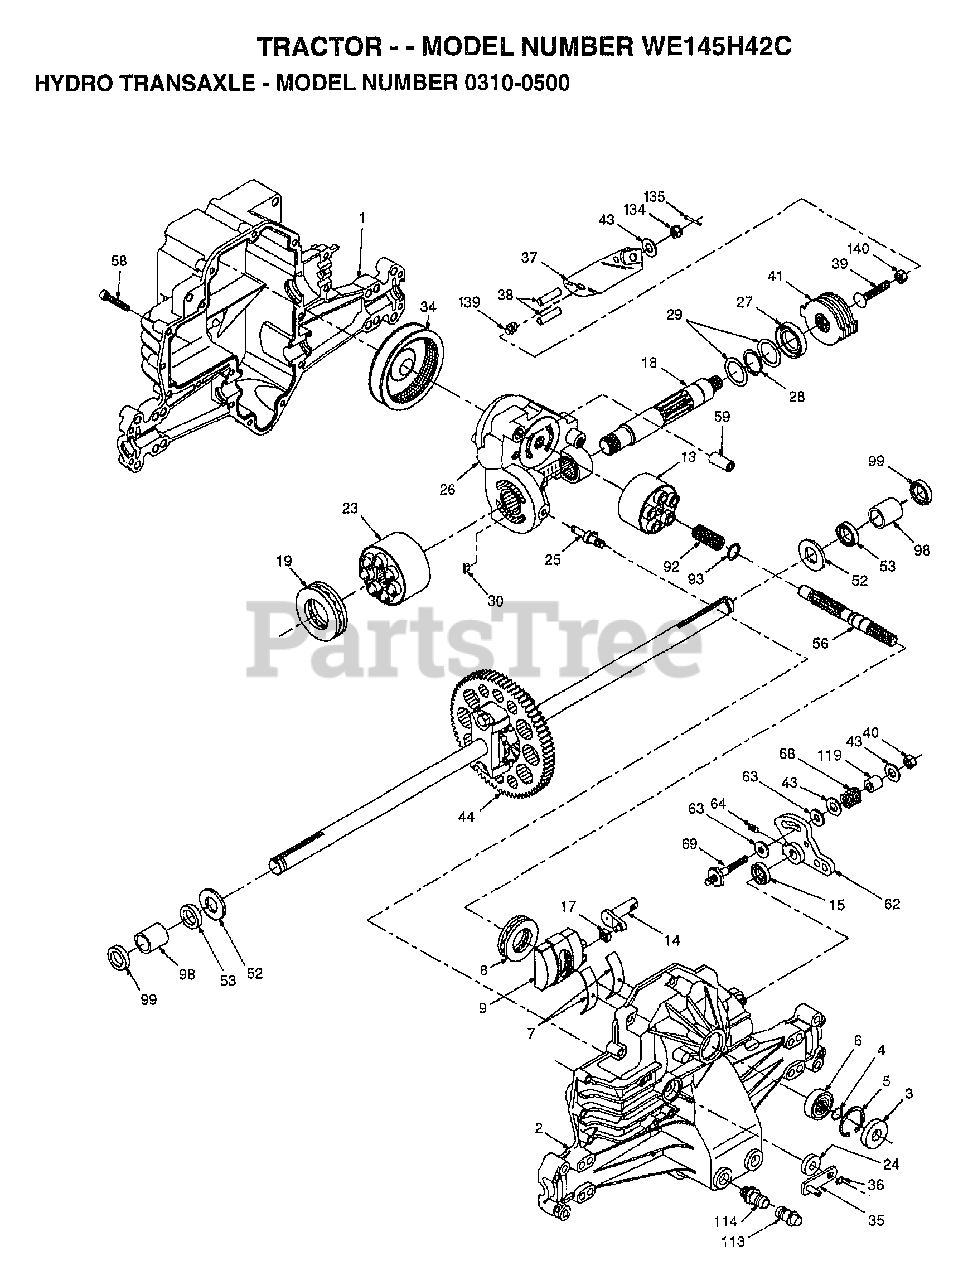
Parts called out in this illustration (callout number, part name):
1	HOUSING.L.44863RM
2	HOUSING.UPR.70122
3	SEAL.9008000-0128
4	RING.RET.2003016.
5	RING.RET.2003052.
6	BEARING.(50552)42X68X16
7	CRADLE- 2003023.
8	BEARING.THU.50551
9	SWASHPLT.2003087.
13	BLOCK.CLYN.70079.
14	ARM.TRUN.2003005.
15	SEAL.9008000-0126
17	GUIDE.2000015.
18	SHAFT.MOTOR.50449
19	BEARING.THU.50552
23	BLOCK.CYLIN.70082
24	SEAL.LIP.45074
25	ACTUATOR.2003555
26	KIT.CEN.SEC.70250
27	SEAL.LIP.45075
28	RING RETAIN 50007
29	WASHER.44872
30	PLATE.BYP.2003554
34	ELEMENT.OIL.44964
35	ARM.BYPASS.50270
36	RING.RETAIN.44870
37	ARM.ACTUAT.23710
38	PIN.ACTUAT.44891
39	BOLT.50316
40	NUT.LOCK.HX.50317
41	KIT.BRAKE.70135
43	WASHER HYD 44130
44	DIFFERNTIAL.70126
52	WASHER.HYD.44875
53	SEAL.HYDRO.45076
56	SHAFT.INPUT.50005
58	BOLT.1/4-20.44876
59	PIN.HYDRO.50002
62	ARM.CONTROL.50254
63	PUCK.DAMPER.50281
64	SCREW.SET.50018.
68	SPRING.HYD.50277
69	STUD.5/16-24.DANA
92	SPRING.2003014.
93	WASHER.2003017
98	BEARING.SLV.50137
99	SEAL.WIPER.50941
113	CAP.VENT.70109
114	O-RING.ASM.70110
119	SPACER.HYD.50278
134	NUT.CAS.HYD.44142
135	PIN.COT.HYD.44101
139	SPRING.COMP.50431
140	NUT.HEX.50269
